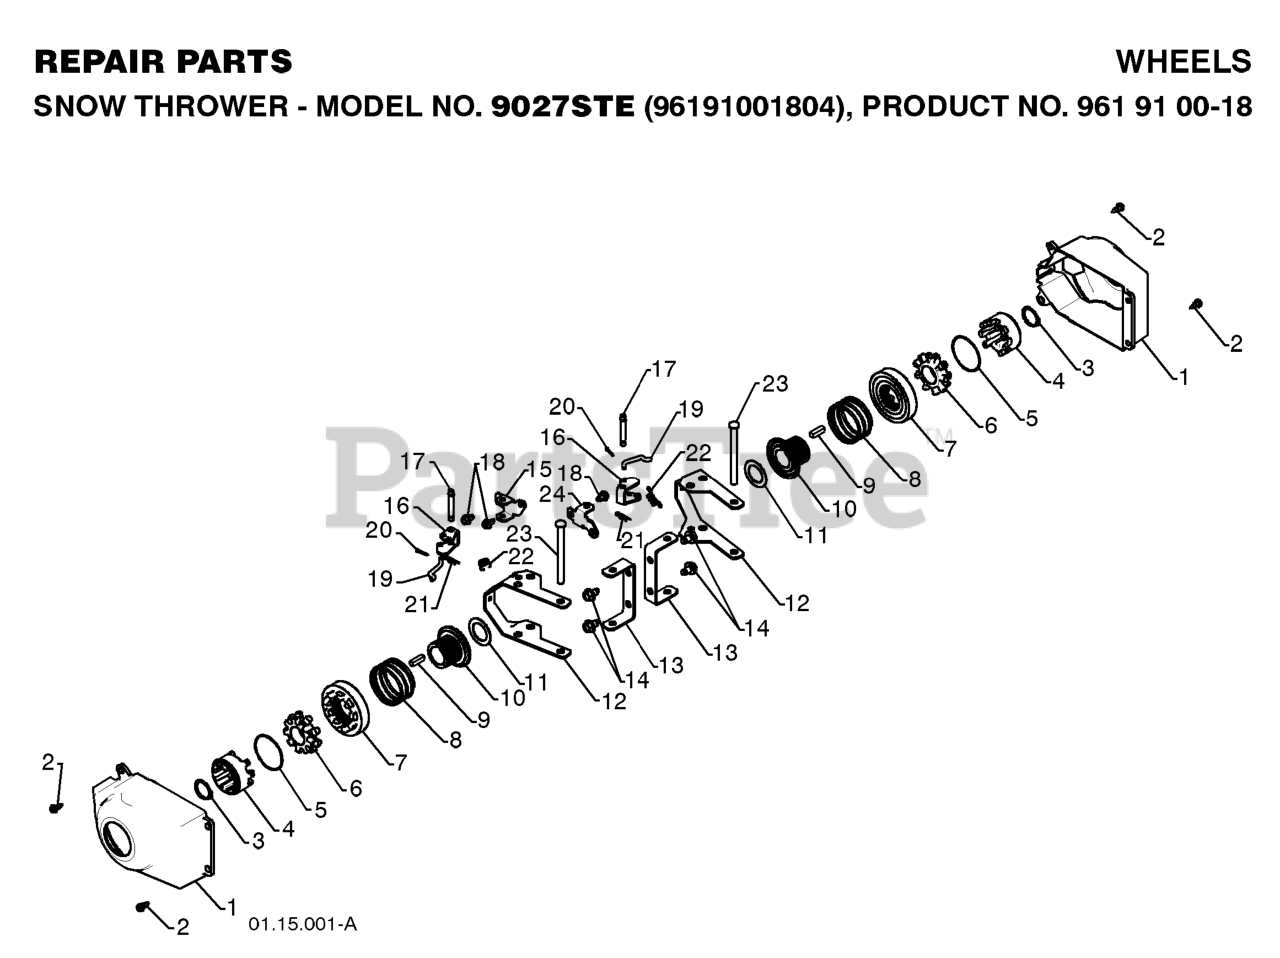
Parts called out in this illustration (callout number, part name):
1	COVER, POWER STEERING
2	SCREW, HEX HEAD, TAPPING
4	RP.DRIVER WHEEL
5	RING, WIRE RETAINER
6	LOBE WHEEL
7	RP.SLIDE.CLUTCH
8	SPRING, CLUTCH SLIDE
9	KEY, SQUARE 1/4 X .875
10	RP.LOBE.AXLE
11	WASHER TRUST 1"
12	YOKE, STEERING
13	BRACKET.STEER.PNT.BLACK
14	Screw 5/16-18 x 1/2 Hex, Self Tapping 5/16-18 x 1/2
15	BRKT.STEER.PIVOT.RH
16	BELLCRANK.STEER
17	PIN, STEERING BELLCRANK
18	SCREW 1/4X20
19	LINK.STEER.YOKE
20	RETAINER CLIP
21	RETAINER CLIP PM
22	SPRING LATCH
23	PIN, STEERING LEVER
24	BRACKET.STEER.PIVOT.LH.YZ
